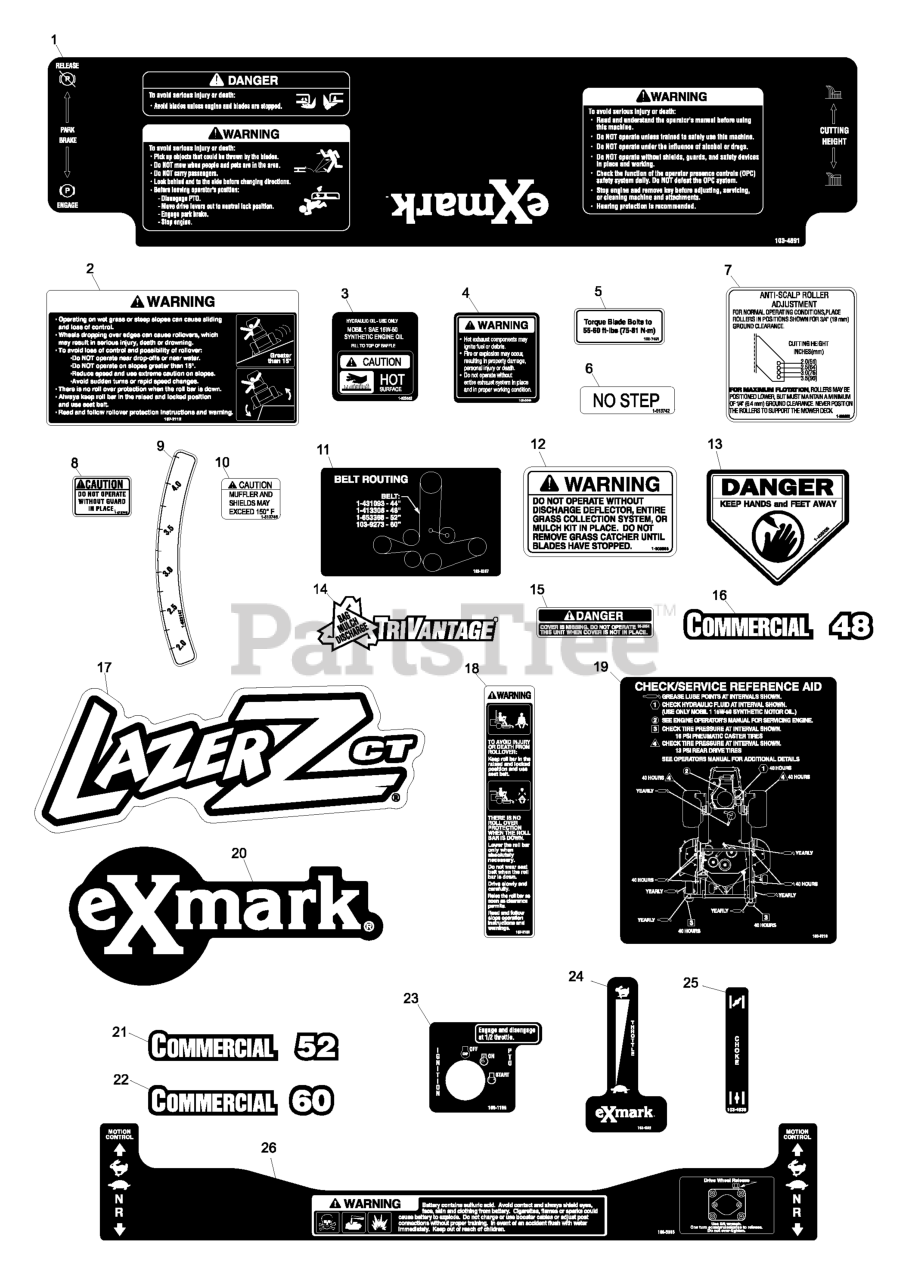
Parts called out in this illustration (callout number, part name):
1	DECAL,CONSOLE LHP
2	DECAL-WARNING
4	DECAL-EXHAUST
6	DECAL,NO STEP
7	DECAL,ANTISCALP
8	DECAL-GUARD
9	DECAL-DECK HEIGHT, INNER
11	DECAL, BELT ROUTING
12	DECAL-WARNING, DISCHARGE
13	DECAL-DANGER
15	DECAL-COVER, MISSING
16	DECAL,COMMERCIAL 48
17	DECAL,LCT MODEL
18	DECAL-WARNING, FOLDING RO
19	DECAL, CHECK/SERVICE LCT
20	DECAL,EXMARK LOGO
21	DECAL,COMMERCIAL 52
22	DECAL,COMMERCIAL 60
23	DECAL,IGNITION/PTO
24	DECAL,THROTTLE
25	DECAL,CHOKE
26	DECAL-WARNING
